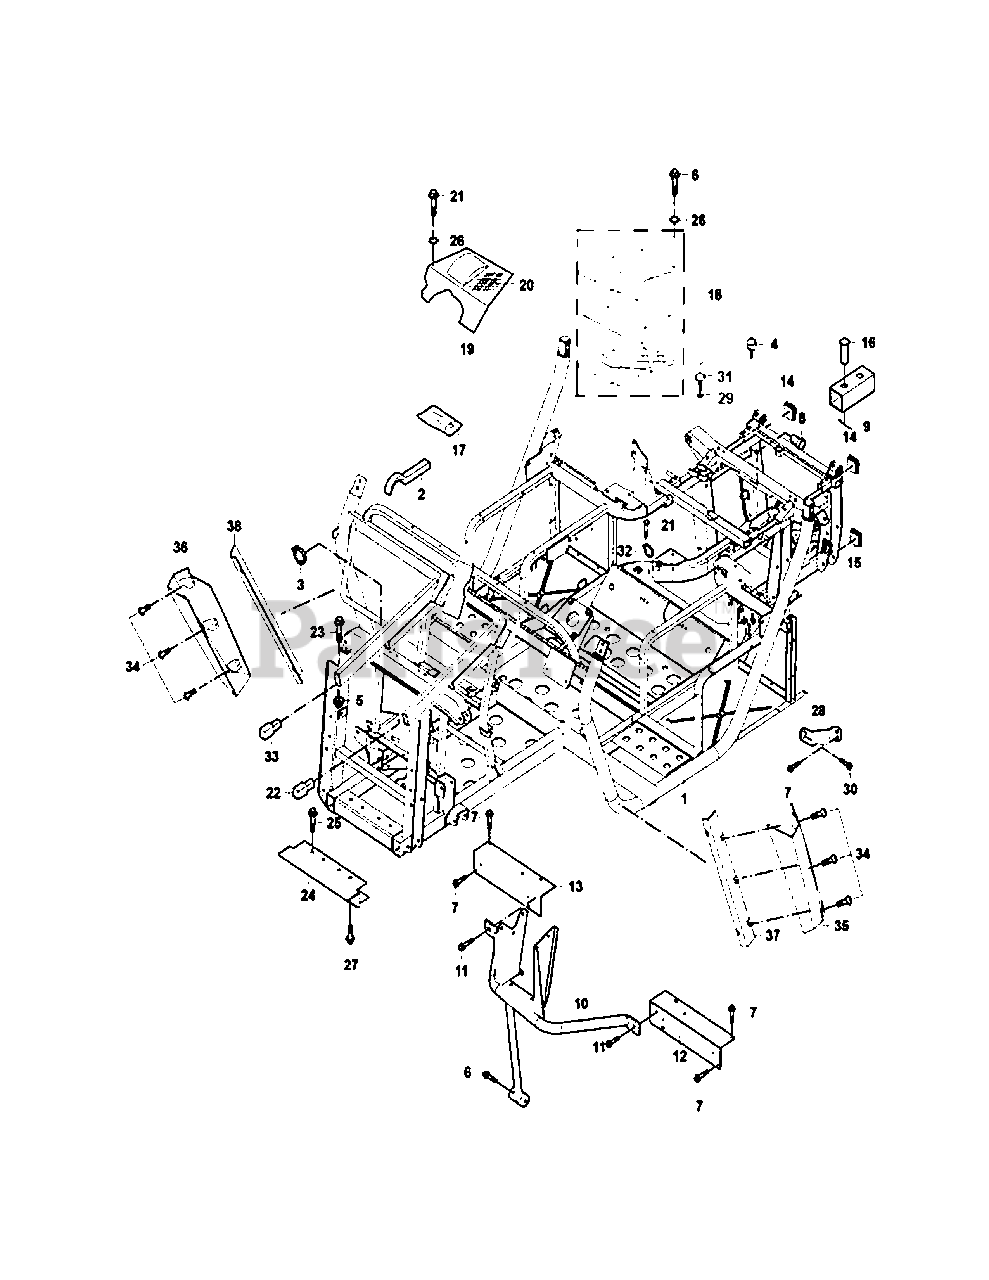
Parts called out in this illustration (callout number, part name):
1	Frame joint parts
2	Shock absorber adjusting wrench
3	Clip9
4	Rubber Cushion (Round)24-28
5	Hexagon flange nut M10×1.25
6	Hexagon Flange Bolt M6×16
7	Hexagon Flange Bolt M8×16
8	Shock Absorber Cushion 24-11
9	R type pin24
10	Middle protective bracket
11	Hexagon flange bolt M10×1.25×20
12	Bracket, left seat
13	Bracket, right seat
14	Frame Pipe Plug 40×25
15	Frame Pipe Plug 60×40
16	Hitch Bar Pin
17	Tool kit
18	Insulation board, muffler
19	Insulation board, rear bridge
20	Insulation paper i
21	Hexagon Flange Bolt M6×16
22	Hinge (L)
23	Hexagon Bolt M10×1.25×55
24	Bumper holder
25	Hexagon flange bolt M12×1.25×35
26	Washer 6×18×1.6
27	Hexagon flange bolt M12×1.25×25
28	Lower installing support, rear bridge
29	Heat Inslation Foam
30	Hexagon flange bolt M10×1.25×20
31	Screw 3.2×11
32	Clip , metal water pipe
33	Mounting bracket,front body cover
34	Cross large plate head screw M6×16
35	Left Fender- Front Cover II
36	Right Fender-Front Cover II
37	Mounting Bracket, Left Fender
38	Mounting Bracket, Right Fender
39	Adjust Damping Washer
40	Nut M8
